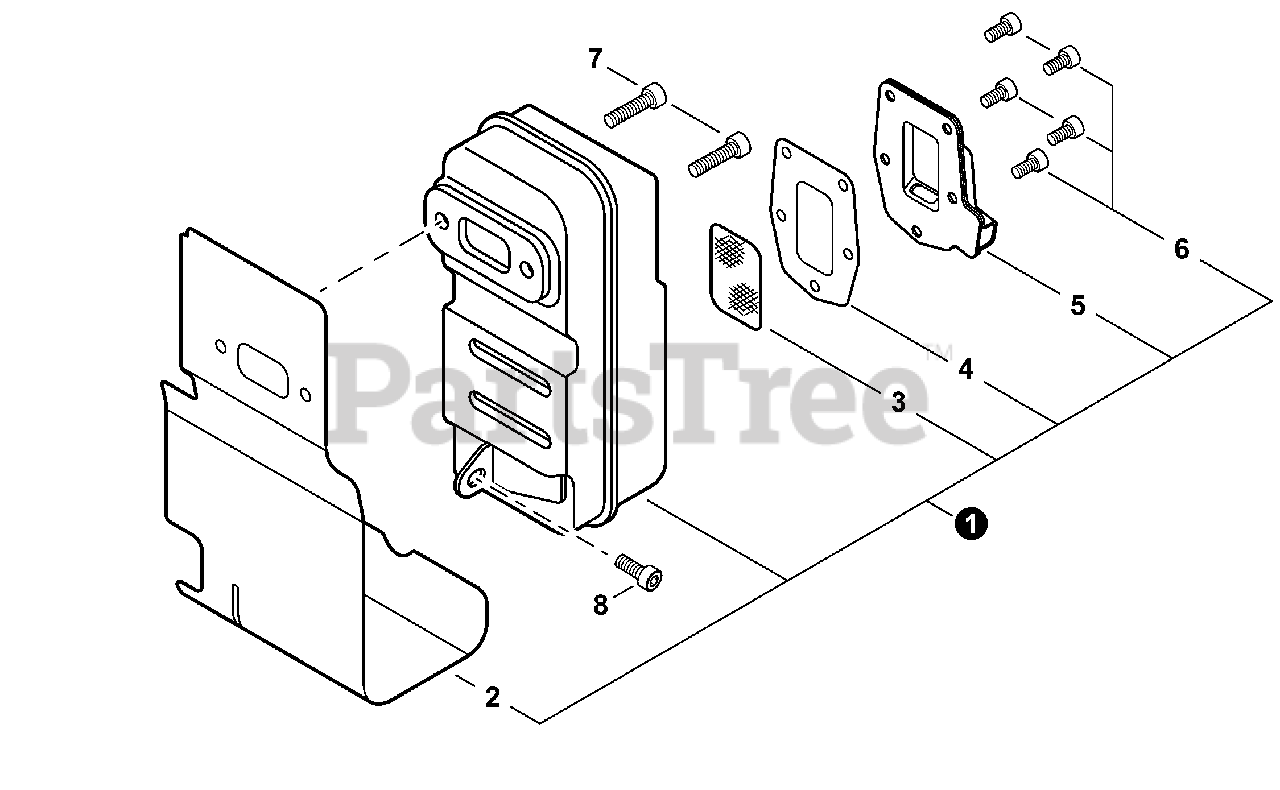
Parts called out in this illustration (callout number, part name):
1	MUFFLER ASSY
2	HEAT SHIELD, EXHAUST
3	SCREEN, SPARK ARRESTER
4	GASKET, EXHAUST
5	GUIDE, EXHAUST
6	BOLT, TORX 4×10
7	BOLT 6×20
8	BOLT, TORX 5×16
